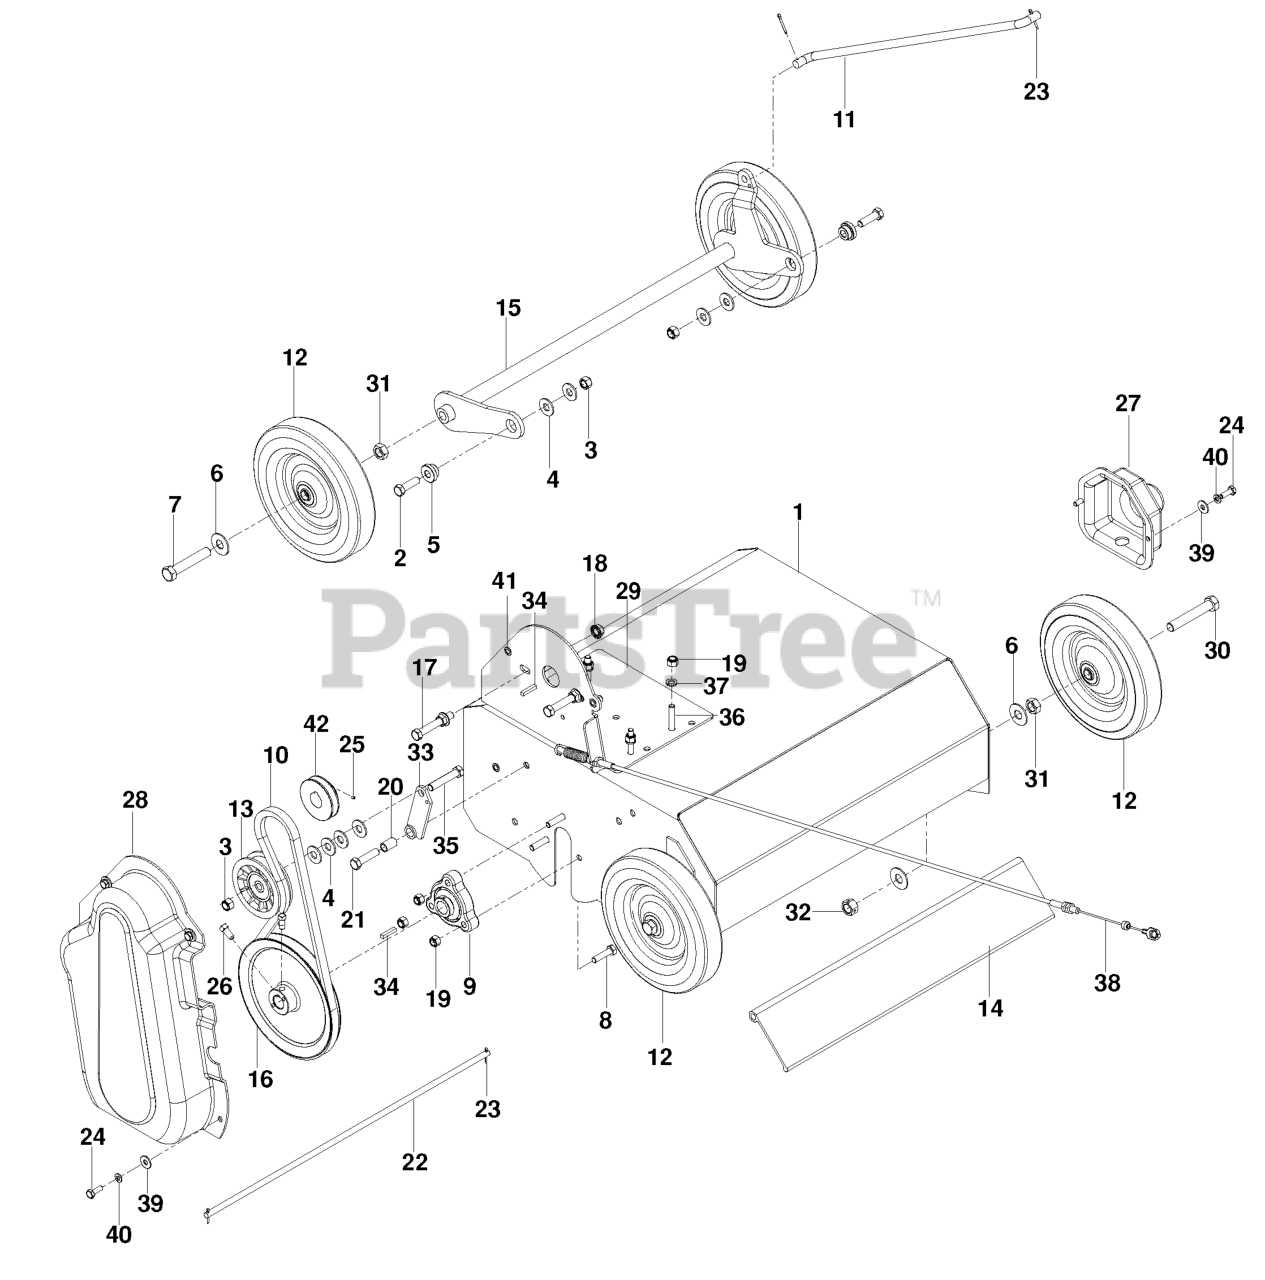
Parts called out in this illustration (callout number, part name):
1	KIT, BODY W/DECALS
2	HCS 3/8C X 1 1/4 GR5
3	NUT 3/8-16 NYLOC
4	WASHER 3/8 FLAT
5	BUSHING RAKE
6	WASHER 1/2 FLAT
7	HCS 1/2C X 2 3/4
8	HCS 5/16C X 1 1/4
9	BEARING, FLANGED
10	BELT, DRIVE RAKE/SLICER DFS
12	WHEEL 8 X 1 3/4 RAKE
13	PULLEY, IDLER RAKE & ZTR
14	DEFLECTOR SHIELD
15	FRONT AXLE ORANGE
16	PULLEY, MAIN SHAFT
17	HCS 3/8C X 2 1/2
18	NUT 3/8C WHIZ
19	NUT 5/16 NYLOC
20	BEARING, ONLITE RAKE/DT
21	HCS 3/8C X 1 1/2
22	DEFLECTOR ROD
23	COTTER PIN 3/32 X 3/4
24	HCS 1/4C X 3/4 HCS
25	KPSS 5/16-18 x 3/8
26	SCREW 5/16C X 5/8 SQ HEAD
27	SHAFT GUARD
28	BELT GUARD
29	BACKING PLATE, BLUE
30	SCREW, 1/2C X 3 HEX CAP
31	NUT 1/2 HEX JAM
32	NUT 1/2-13 HEX CNTRLK GR 5 ZD
33	IDLER, ARM, BLACK
34	KEY, 3/16 SQUARE
35	HCS 3/8C X 2
36	HCS 5/16C X 1 3/4
37	WASHER.LOCK.HVY.HLCL.SPR.5/16
38	CABLE POWER RAKE
39	WASHER 1/4 FLAT
40	LOCKWASHER 1/4"
41	KNURLED INSERT
42	ENGINE PULLEY - 5.5 HP
